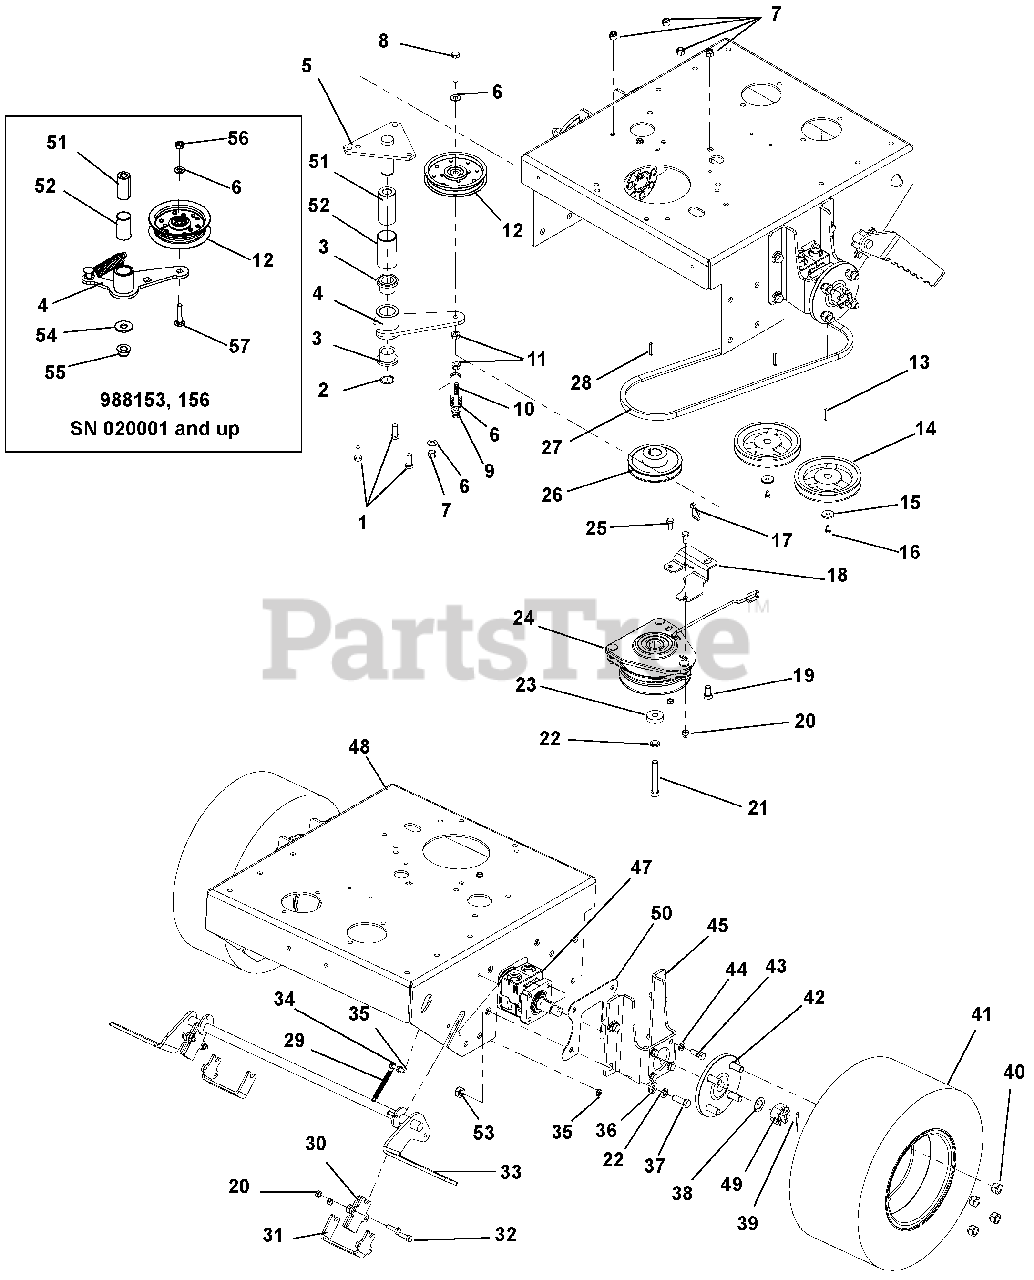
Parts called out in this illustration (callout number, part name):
1	BOLT-HEX .38-16 1.00 GR5
2	SNAP RING, 1.00 X .042 EXT
3	BRG, FLG 1.00 X 1.25 X 1.00
4	WLDT, IDLER ARM (SN 000101 - 020000)
5	WLDT, IDLER PIVOT MOUNT (SN 000101 - 020000)
6	WASHER, .406 X .813 X .065 FLAT Y
7	NUT-LOCKING-NYLON .38-16
8	BOLT, HEX .38-16X2.50 GRADE 5
9	BLT-HEX .38-16X3.00 HEX 8 YWZC
10	SPRING, EXT .900X.135X4.50 Y (SN 000101 - 020000)
11	NUT-SPIN LOCK-FLANGE .375-16
12	PULLEY, FLAT 4.50 X .375 W/BRG (SN 000101 - 020000)
13	KEY, M5 X M5 X M30 RD
14	ASSY, PUMP PULLEY W/SET SCREW (SN 000101 - 020000)
15	WASHER, .250 WIDE HEAVY FLAT Y
16	BOLT, M6 X 1.00 X 10 HEX 8.8 Y
17	CABLE TIE, .15 X 8.50
18	PLATE, CLUTCH DOG
19	BOLT, 7/16-14 X .750 HEX 5 Y
20	NUT-LOCKING-NYLON .312-18
21	BOLT, HEX .44-20 X 3.00 G5
22	WASHER-LOCKING .44X.109 REGULAR (SN 000101 - 020000)
23	SPACER, .468 X 1.38 X .375 Y
24	CLUTCH ASSY, OGURA
25	BOLT, HEX .31-18 X .75 GR5
26	PULLEY, V-BELT 4.45X1.00 W/KEY (SN 000101 - 020000)
27	BELT, HA 55.1 EL AMD OHR (SN 000101 - 020000)
28	KEY, .250 X .250 X .995 TPR
29	SPRING, EXT .375 X .055 X 2.25 Y (SN 000101 - 020000)
30	SHOE, BRAKE SYSTEM FLOAT WALK (988153, 154, 155, 156, 157, 158)
31	BRAKE ROD SUPPORT (988159, 169)
32	BOLT, HEX .31-18 X 1.00 GR5
33	WLDT, BRAKE SYS FLOAT HYDRO (988154, 155, 157, 158)
34	BOLT, HEX .25-20 X 1.25 GR5 (SN 000101 - 020000)
35	LOCKNUT, 1/4-20 WHIZ Y (SN 000101 - 020000)
36	WASHER, .468 X 1.00X.125 FLAT Y
37	BOLT, HEX .44-14 X 1.25 GR5
38	BUSHING, MACH .750X1.25X.048 Y
39	PIN, COT .125 X 1.50 EXTP Y
40	NUT, 1/2-20 LUG C
41	ASSY, WHEEL & TIRE 16 X 7.5-8 (988154, 155, 157, 158)
42	ASSY, WHEEL HUB
43	BOLT, 3/8-16 X 1 GR8 BLACK
44	WASHER, .38 x .094 REG
45	BRKT, MOTOR MOUNT FLWLK (988153, 154, 155, 156, 157, 158) (SN 000101 - 020000)
46	BRKT, WHEEL MOTOR WLDT (988159, 169)
47	MOTOR, HYDRAULIC WHEEL
48	ASM, FRAME W/DECALS 36" GRAVELY (988153, 156) (SN 000101 - 020000)
49	NUT, .75 UNF2B HEX SLOT JDS14
50	ENGINE BED DOUBLE PLATE (988159, 169)
51	BSHG, SPCR .505/.500 X .999/.996 X 2.05/2.03 PM (988153, 156) (SN 021000 and up)
52	BSHG, 1.00 X 1.125 X 1.936 (988153, 156) (SN 021000 and up)
53	NUT-LK-NYL .44-14 YWZC
54	WSHR-FL-STL .563X1.38X.109YWZC (988153, 156) (SN 021000 and up)
55	NUT-LK-NYL-FLG .50-13 YWZC (988153, 156) (SN 021000 and up)
56	NUT-LK-CTR .38-16 YWZC (988153, 156) (SN 021000 and up)
57	BLT-RDHDSQNK .38-16X1.75 G5YZ (988153, 156) (SN 021000 and up)
